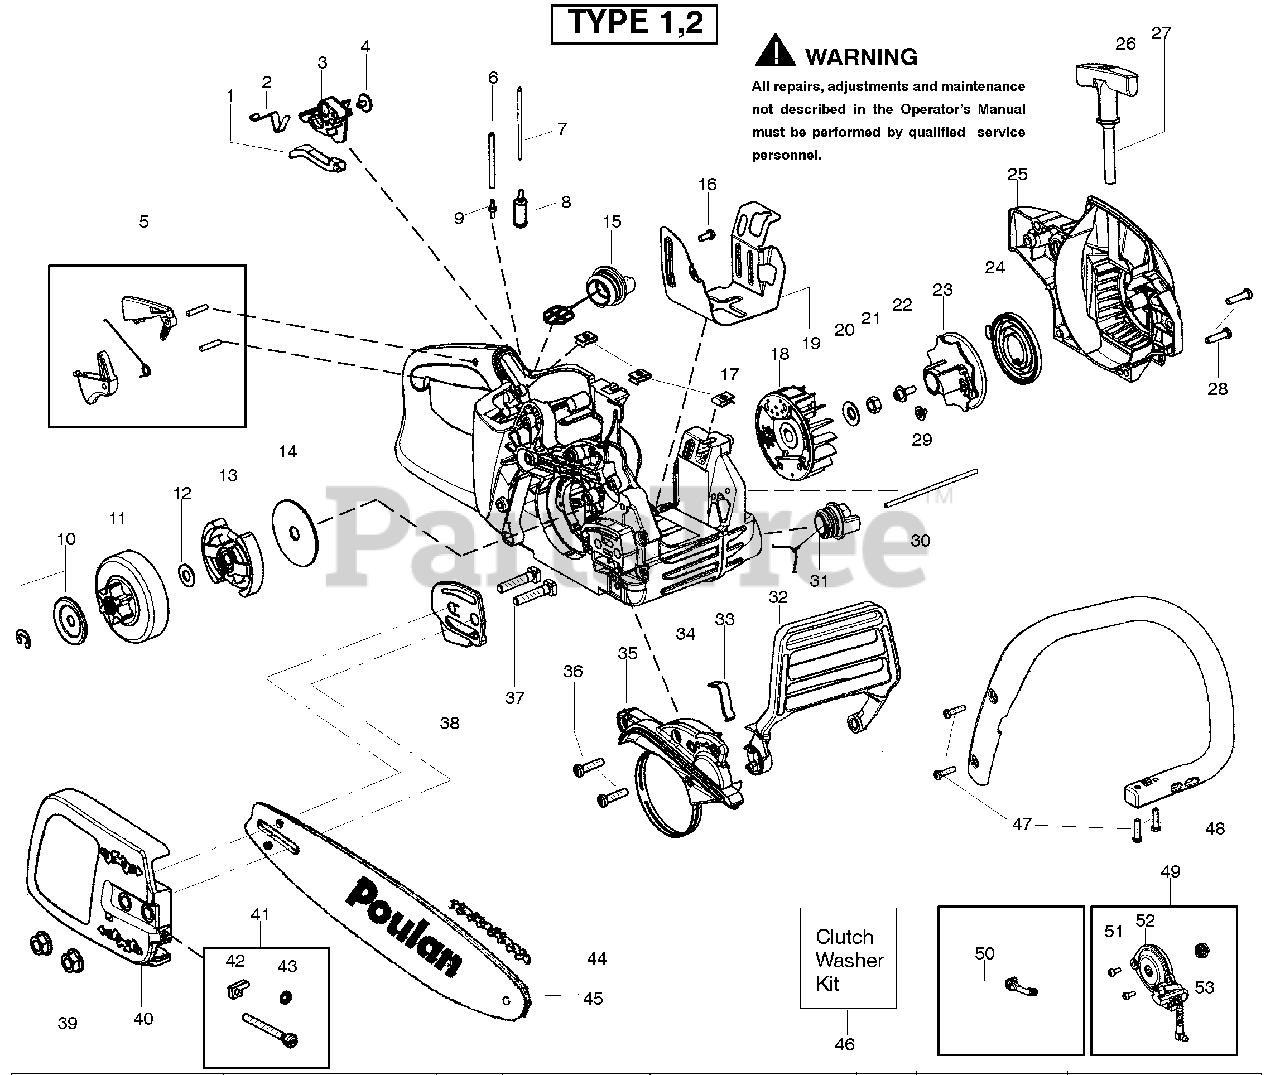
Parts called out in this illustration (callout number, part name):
1	Knob-Choke
2	Spring-Ign. Switch
3	Lever-Ign. Switch
5	Kit-Trigger/Lockout
6	Kit-Fuel Line (Large)
7	Kit-Fuel Line (Small)
8	Assy-Fuel Pick Up
9	Fitting-Fuel line
10	Kit-Clutch Washer
11	Assy-Clutch Drum 3/8"
12	Kit-Clutch Washer
13	Assy-Clutch
14	Washer-Large Clutch
15	Assy-Fuel Cap w/ret
17	Nut-"U" type speed
18	Assy-Flywheel
19	Shield-Heat
20	Washer-Flywheel
21	Nut-Flywheel
23	Pulley-Starter
24	Spring-Starter
25	Housing-Fan
26	Handle-Starter
27	Kit-Rope
30	Assy-Oil Vent
31	Assy-Oil Cap w/ret.
32	Handguard
33	Spring-Handguard
34	Assy-Chassis
35	Kit-Chainbrake
37	Bolt-Bar
38	Plate-Bar
40	Assy-Clutch Cover
41	Kit-Bar Adjust
42	Pin-Bar Adjust
43	Retainer-Bar Adjust
44	Accy-14" Chain
45	Accy-14" Bar
46	Kit-Clutch Washer
48	Handle-Front
49	Kit-Oil Pump
50	Assy-Oil Pick Up
52	Assy-Oil Pump
53	Gear-Worm
